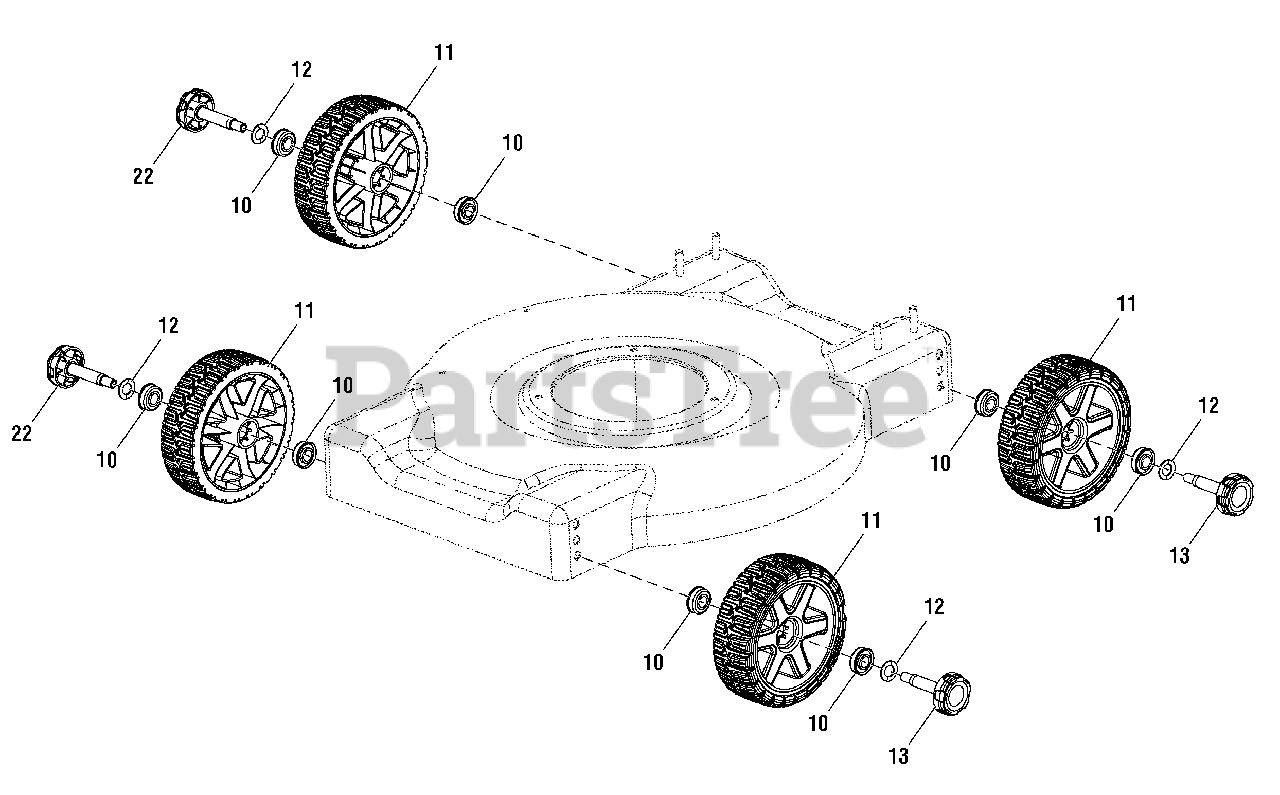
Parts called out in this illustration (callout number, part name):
10	BEARING
12	WASHER, Wave Spring, 12
13	AXLE, Assembly, Left
22	AXLE, Assembly, Right
